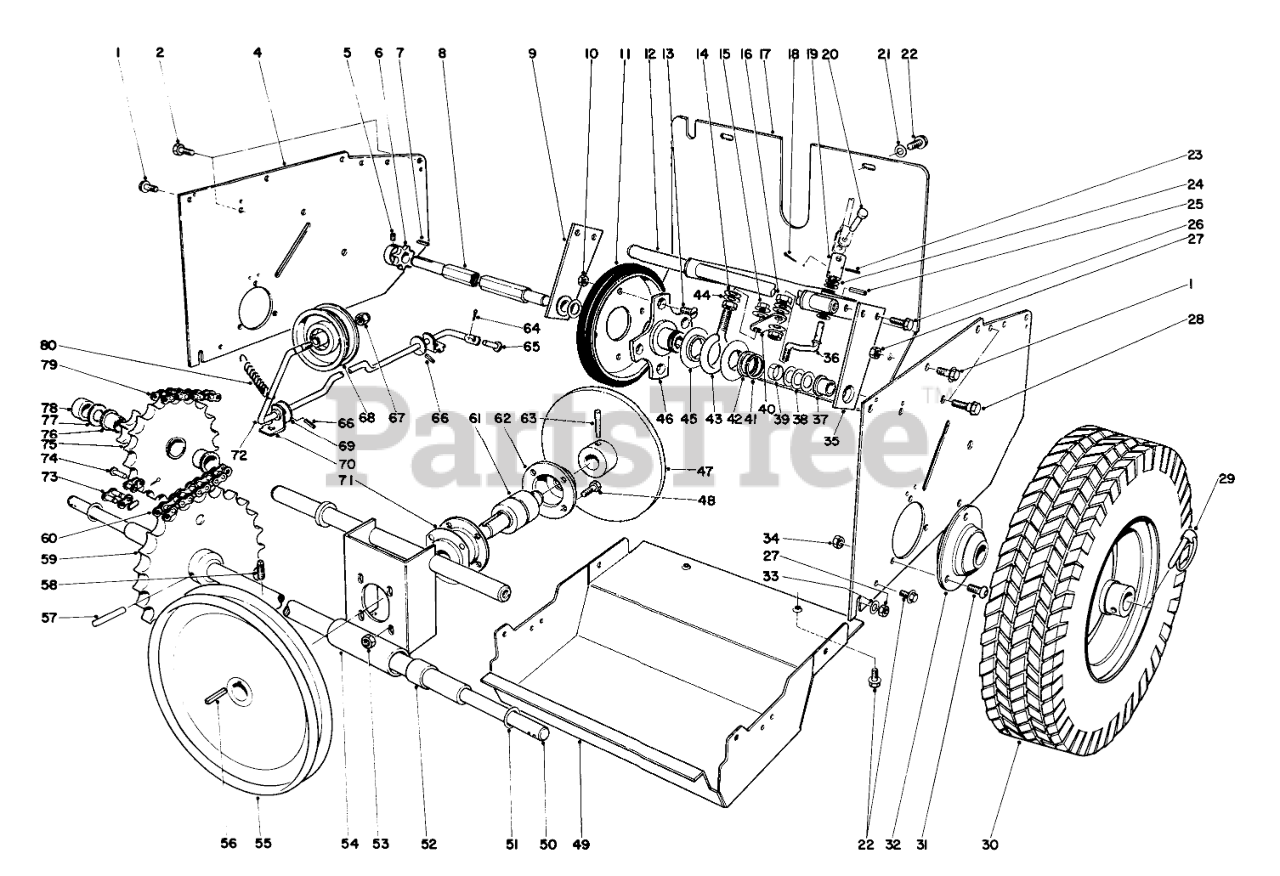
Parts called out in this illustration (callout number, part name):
1	SCREW-HHF
2	SCREW-HWH,THD ROLL
4	Side Plate
5	Set Screw
6	SPROCKET
8	FRICTION WHEEL SHAFT
9	Hex Shaft Mount (Incl. Ref. #37)
10	Nut
11	Disc
12	Bracket Dead Shaft
13	5/16-18X5/8 FLT HD MS
14	WASHER-SPRING
15	NUT-LOCK, FLANGE
16	Locknut
17	REAR COVER R
18	PIN-COTTER
19	U JOINT TUBE
20	CLEVIS PIN
21	WASHER-FLAT
22	Screw, Self-tapping
23	PIN-SPRING
24	Spacer
25	PIN-ROLL
26	Hex Hd. Screw
27	NUT-HEX
28	SHOULDER SCREW
29	PIN-LYNCH
30	Wheel
31	SCREW-HSBH
32	Bearing Flange
33	WASHER-FLAT
34	NUT-LOCK
35	Hex Shaft Mount (Incl. Ref. #37)
36	CONNECTION ROD
37	BUSHING
38	WASHER-FLAT
39	SPLIT SPACER
40	SHIFT ROD PIVOT
41	Snap Ring
42	WASHER-THRUST
43	SLIDER RING COLLAR
44	WASHER-FLAT
45	SLIDER RING
46	Hub Traction Disc
47	FRICTION PLT WA
48	SCREW-HH
49	LOWER SHIELD R
50	Axle Shaft
51	WASHER
52	BUSHING
53	NUT-KEPS
54	Bulkhead (Incl. Ref. 73)
55	Pulley
57	Groove Pin
58	SCREW-SET, SQH
59	Sprocket
60	Chain Lower
61	Friction Plate Shaft
62	HOUSING BEARING
63	Groove Pin
64	PIN-COTTER
65	PIN-CLEVIS
66	PIN-ROLL, SLOTTED
68	PULLEY-IDLER
69	WASHER-FLAT
70	Bracket-Belt Clutch
72	Auger Clutch Rod
73	LINK-CONNECTING
74	1/4 OFFSET LINK
75	Sprocket Hub (Incl. Ref. #75)
76	3/4ID X 3/4LG BSHG
77	WASHER-THRUST
78	Spacer Idler
79	1/4 X 42 CHAIN W/LINK
80	EXTENSION SPRING
